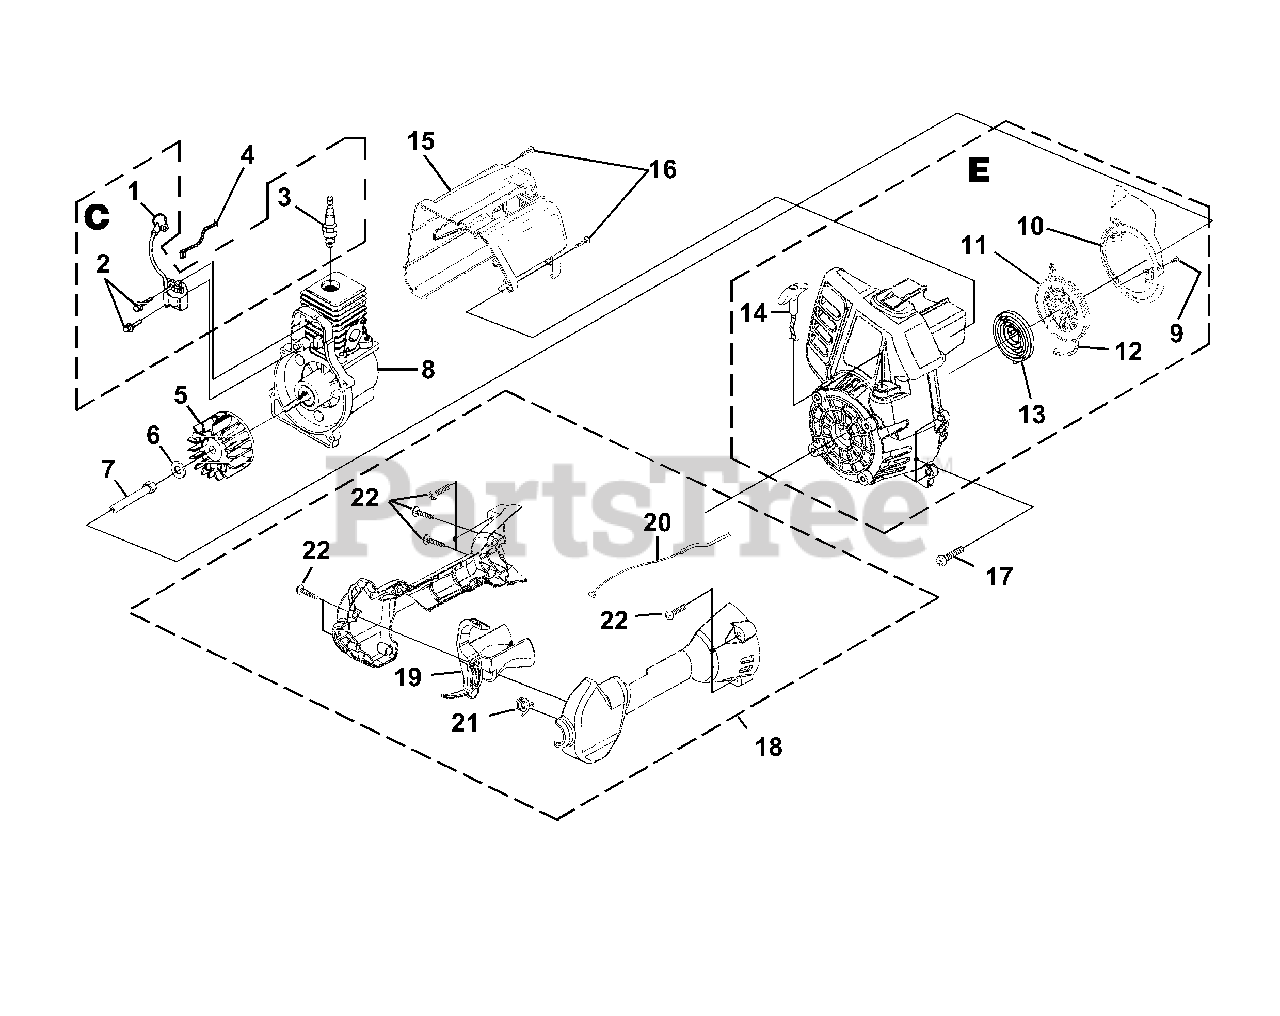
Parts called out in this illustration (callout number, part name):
1	TERMINAL & COVER
2	SCREW-Taptite (8-32 X 1")
3	SPARK PLUG
4	LEAD-Electrical
5	ROTOR KIT
6	WASHER-Flat
7	CONNECTOR-Drive (.250)
8	SHORT BLOCK
9	SCREW-Thread Form (8-16 X 1/2")
10	BAFFLE-Air
11	PULLEY-Starter
12	ROPE-Starter (42")
13	SPRING & CONTAINER
14	GRIP-Starter (Yellow)
15	HOUSING-Rear Kit
16	SCREW-Taptite (10-14 X 3/4")
17	SCREW-Taptite (10-24 X 3/4")
18	CONTROL HANDLE ASSY.
19	TRIGGER
20	CABLE-Throttle
21	SPRING
22	SCREW-Truss Hd. (10-14 x 1")
C	IGNITION KIT
E	COMPLETE STARTER ASSEMBLY
